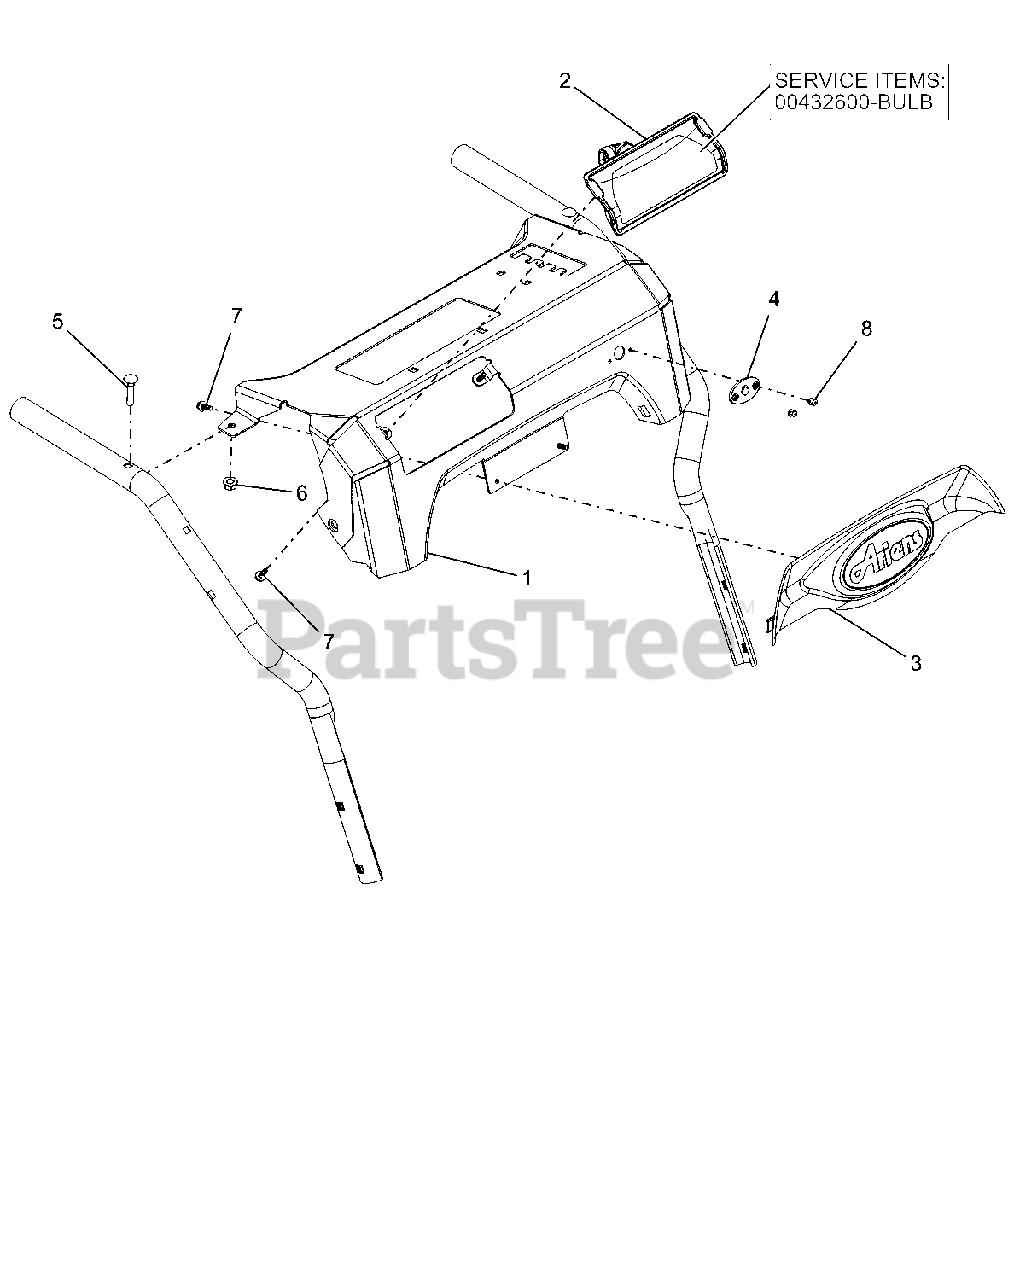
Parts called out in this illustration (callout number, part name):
1	CTRL PANEL W/DECAL-SM DASH DLX
2	BULB, LIGHT-HALOGEN 20W
2	HEADLIGHT ASY, HALO 20W 2SHOT
3	BEZEL, DASH-ARIENS SM DASH
4	BSHG, CHUTE CRANK
5	BLT-RDHDXLSQNK.25-20X1.25 G5ZC
6	@NUT-LK-TOP-FLG .25-20 YWZC
7	SCR-TAP #10X.50 BOSS INDHXHD
8	RVT-POP #43 .125X.313 STL ZINC
